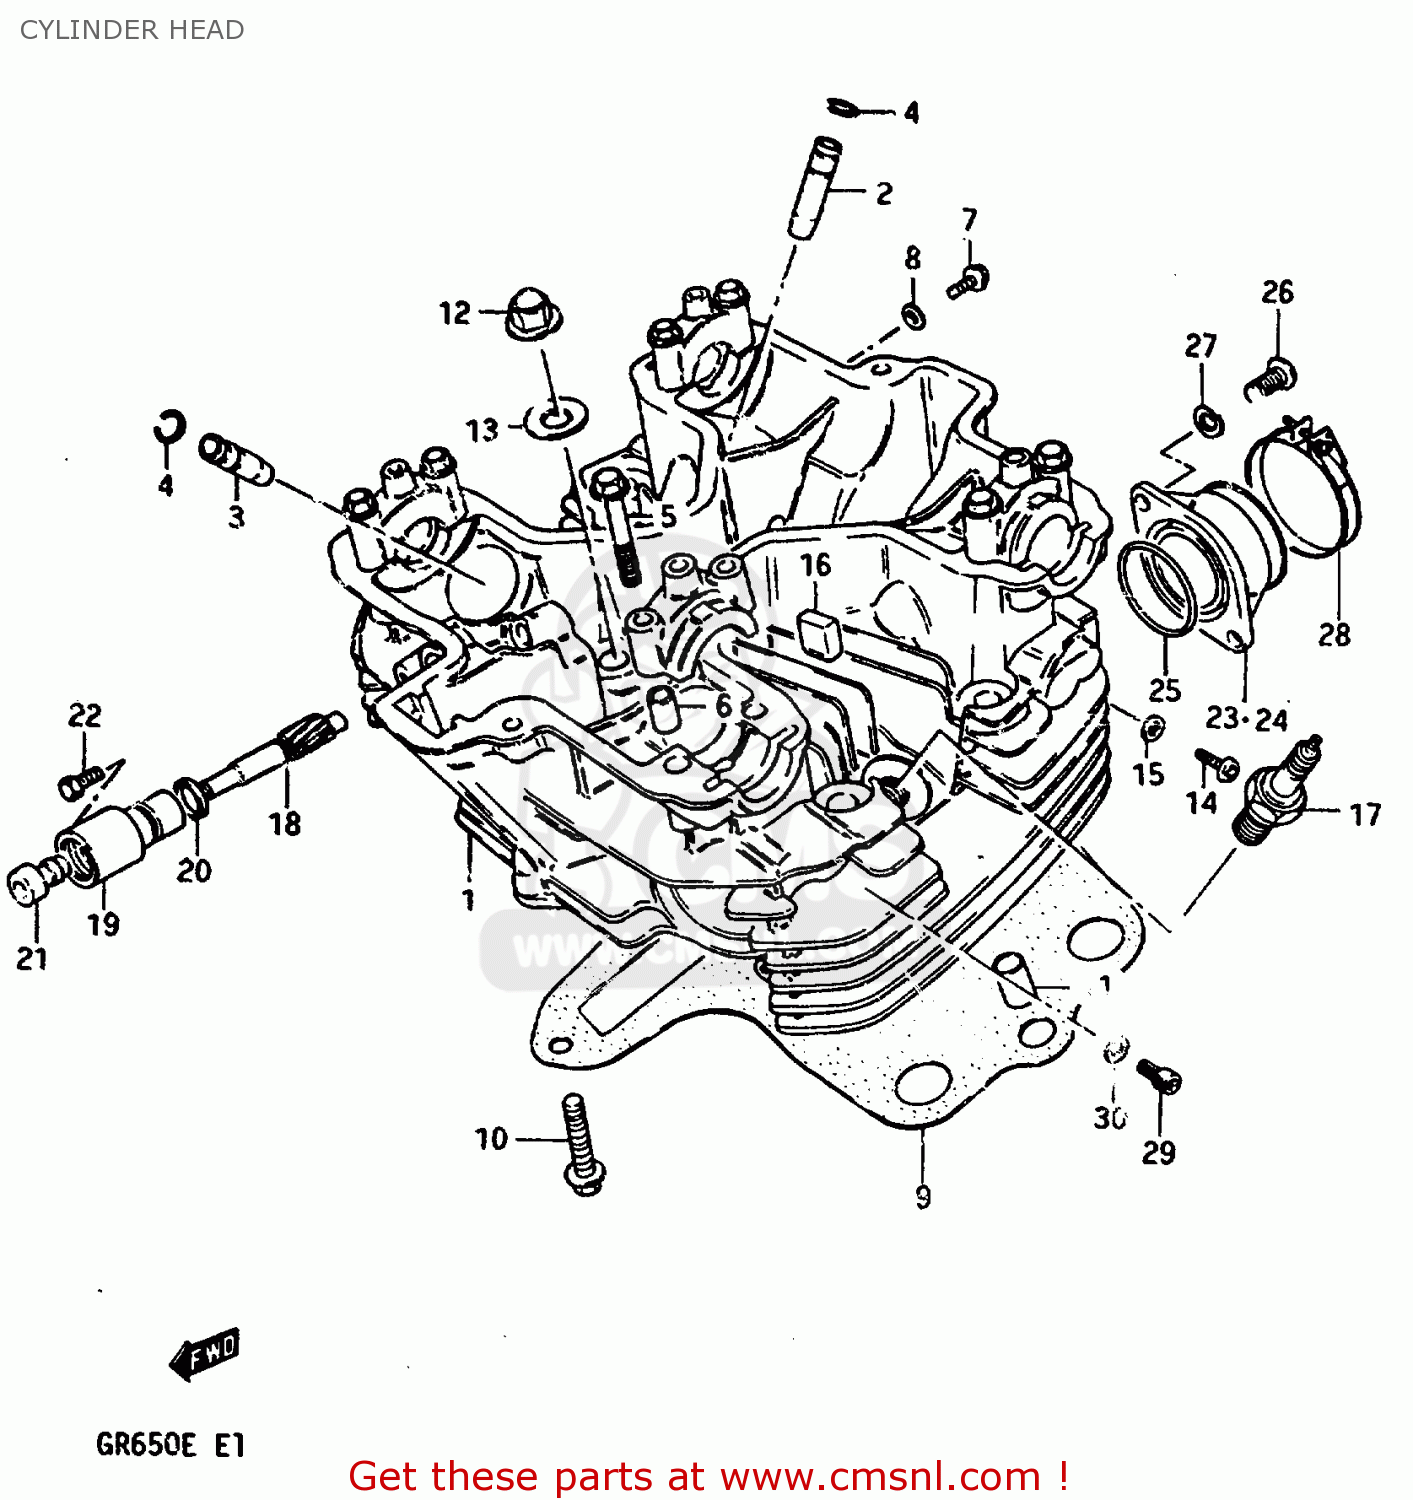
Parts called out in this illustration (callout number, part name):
1	HEAD,CYLINDER
2	GUIDE,INTAKE VALVE
3	GUIDE,EXHAUST VALVE
4	RING,SNAP
5	BOLT(6X39)
6	PIN(6.2X8X11)
7	BOLT 6X12
8	WASHER
9	GASKET,CYLINDER HEAD
10	BOLT
11	PIN
12	NUT
13	GASKET(10.5X22X2) (NAS)
14	SCREW
15	GASKET(5.3X9.3X1.2) (NAS)
16	PAD,CYLINDER HEAD
17	SPARK PLUG D8EA
18	GEAR,TACHOMETER DRIVEN
19	SLEEVE
20	SEAL,TACHOMETER DRIVEN
21	SEAL,OIL(5X12X8)
22	SCREW(5X12)
23	PIPE,INTAKE,R
24	PIPE,INTAKE,L
25	O-RING (D:2.4 ID:39.7)
26	SCREW
27	LOCK WASHER
28	CLAMP
29	BOLT
30	WASHER
